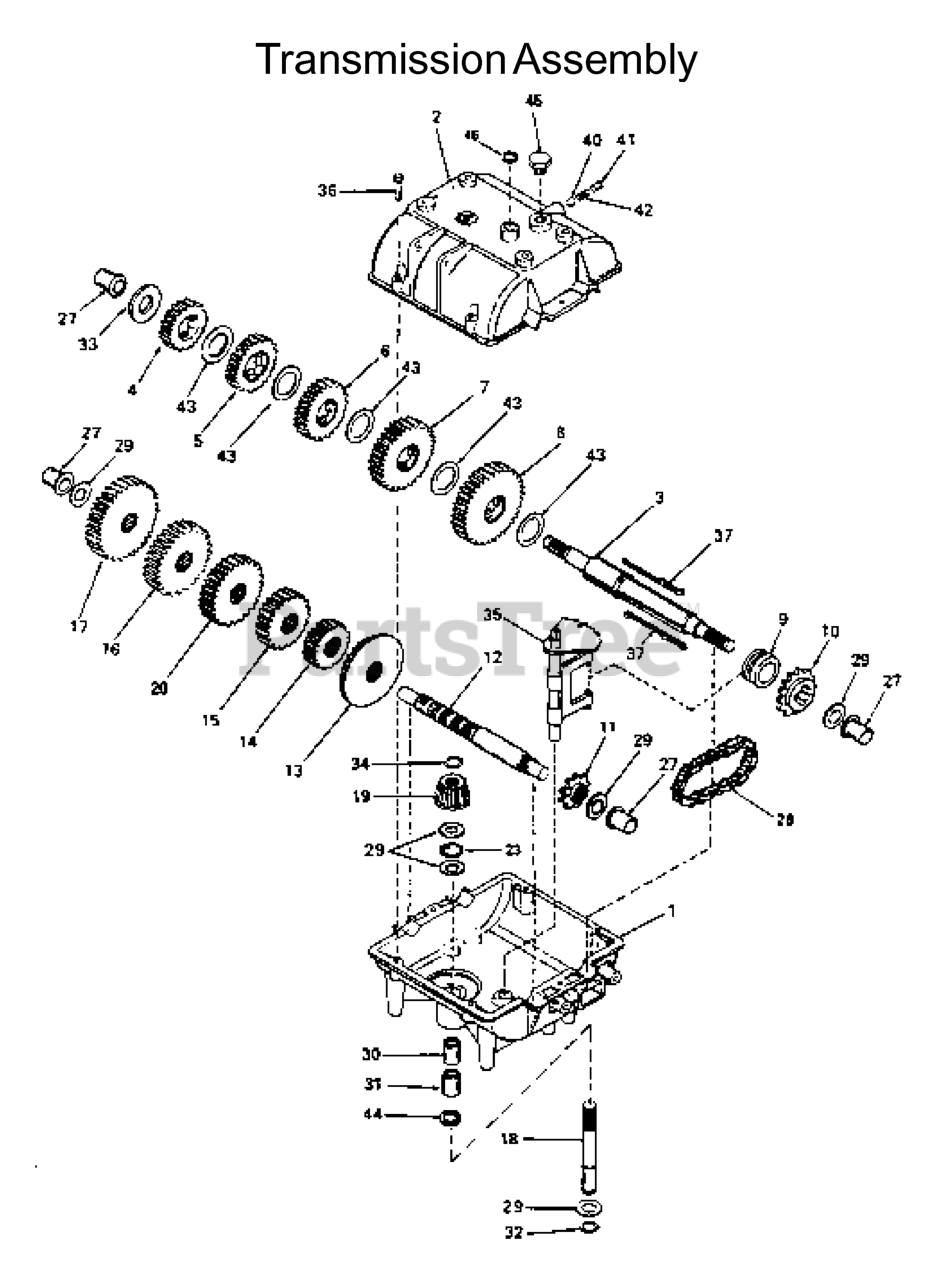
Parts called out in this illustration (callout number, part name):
1	TRANSMISSION CASE
2	TRANSMISSION COVER
3	OUTPUT & BRAKE SHAFT
4	SPUR GEAR (27 TEETH)
5	SPUR GEAR (30 TEETH)
6	SPUR GEAR (32 TEETH)
7	SPUR GEAR (35 TEETH)
8	SPUR GEAR (37 TEETH)
9	SHIFT COLLAR
10	SPROCKET (18 TEETH)
11	SPROCKET (9 TEETH)
12	COUNTERSHAFT
13	GEAR, BEVEL (42 TEETH)
14	SPUR GEAR (12 TEETH)
15	SPUR GEAR (15 TEETH)
16	SPUR GEAR (20 TEETH)
17	SPUR GEAR (23 TEETH)
18	INPUT SHAFT
19	INPUT BEVEL PINION
20	SPUR GEAR (18 TEETH)
23	THRUST BEARING
27	BUSHING, FLANGED
28	CHAIN, ROLLER #41 24 LINK
29	THRUST WASHER
30	NEEDLE BEARING
31	NEEDLE BEARING
32	RETAINING RING
33	WASHER, THRUST
34	RETAINING RING
35	SHIFT ROD & FORK
36	W-FLANGED HEX HD THREADFOR
40	STEEL BALL 5/16"
41	SET SCREW 3/8-16 X 3/8"
43	WASHER THRUST
45	SWITCH, TRANS
46	SEAL, SQUARE CUT
47	TRANSMISSION WB
